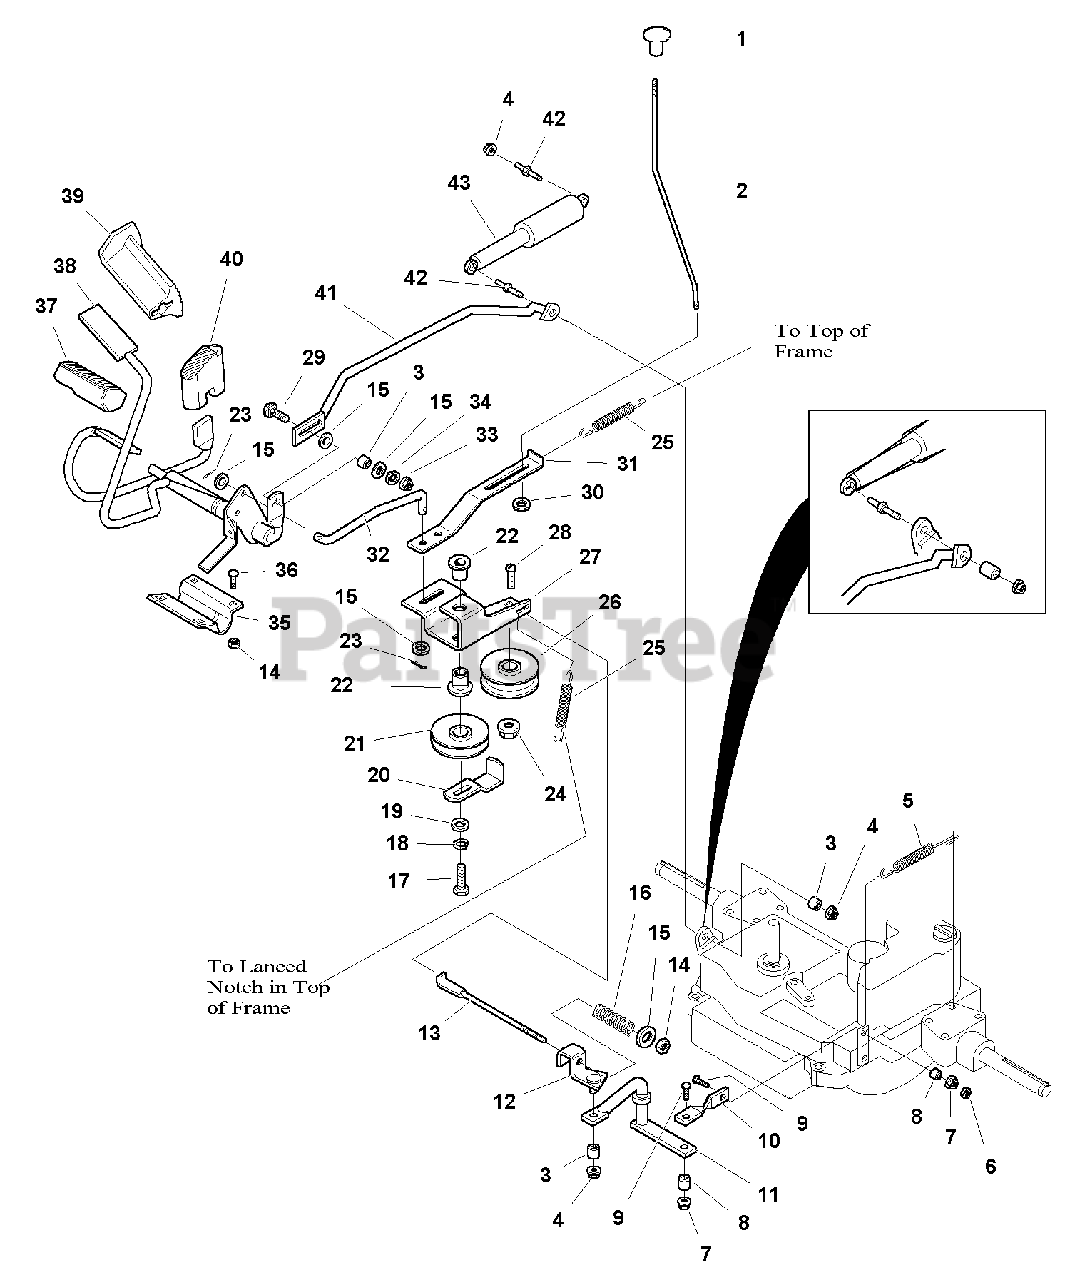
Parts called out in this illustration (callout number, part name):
1	KNOB, Plastic, Parking Brake
2	ROD, Parking Brake
4	NUT, Hex Flange Lock, 5/16-18
5	SPRING, Brake Return
6	LOCK NUT, Center, 1/4-20
7	NUT, Hex Flange Lock, 1/4-20
9	CAPSCREW, Hex Head, 1/4-20 x 1
12	GUIDE, Brake Rod
14	NUT, Hex Nylon Lock, 5/16-18
15	WASHER, Plain, 5/16
17	CAPSCREW, Hex Head, 3/8-16 x 1-3/4
18	LOCKWASHER, 3/8
19	WASHER, Plain, 3/8
21	PULLEY, Idler, V, 3" OD
22	BUSHING, 5/8
23	COTTER PIN, 1/8 x 3/4
24	NUT, Hex Flange Whiz Lock, 3/8-16
26	PULLEY, Backside Idler, 3-1/4" OD
27	BRACKET, Idler
28	CARRIAGE BOLT, 3/8-16 x 1-3/4
29	CARRIAGE BOLT, 5/16-18 x 1
30	WASHER, Plain, 1/4
31	LEVER, Parking Brake
32	ROD, Clutch
33	NUT, Hex, Full, 5/16-18
34	LOCKWASHER, 5/16
35	CLAMP, Tube
36	CARRIAGE BOLT, 5/16-18 x 3/4
37	PAD, Foot Pedal, Forward
38	FOOT PEDAL & BRAKE ARM ASSEMBLY
39	PAD, Brake Pedal
40	PAD, Foot Pedal, Reverse
41	ROD, Control
42	STUD, Shock Mounting
43	SHOCK ABSORBER
